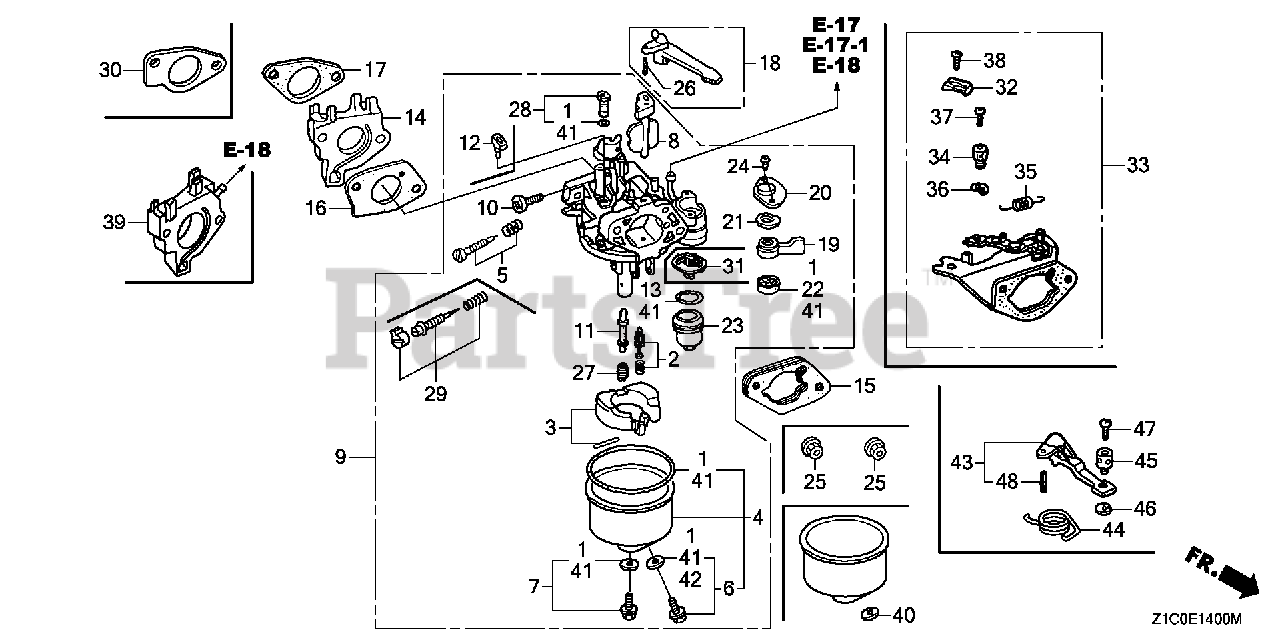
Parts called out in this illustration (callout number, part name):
2	VALVE SET, FLOAT
3	FLOAT SET (CARBURETOR NO.)
4	CHAMBER SET, FLOAT
6	SCREW SET, DRAIN (Honda Code 1672187). (CARBURETOR NO.)
7	SCREW SET
8	CHOKE SET (CARBURETOR NO.)
9	CARBURETOR ASSY. (BE85Z A)
10	SCREW, THROTTLE STOP
11	NOZZLE, MAIN (CARBURETOR NO.)
13	GASKET, FUEL STRAINER CUP
14	INSULATOR, CARBURETOR
15	SPACER, CARBURETOR
16	GASKET, CARBURETOR
17	GASKET, INSULATOR Use up to Engine SN 2949254.
18	LEVER, CHOKE (STD)
19	LEVER, VALVE
20	PLATE, LEVER SETTING (CARBURETOR NO.)
21	SPRING, PETCOCK LEVER (CARBURETOR NO.)
22	GASKET, VALVE
23	CUP, FUEL STRAINER
24	SCREW, PAN (3X6)
26	PIN, SPRING (2X12)
27	JET, MAIN (#95)
27	JET, MAIN (#100) Use from Engine SN BE87A A to BE87A A.
27	JET, MAIN (#98) Use from Engine SN BE87A A to BE87A A.
28	JET SET, PILOT (#40)
29	SCREW SET (Honda Code 4219879). (CARBURETOR NO.)
41	GASKET SET (INCLUDE 16173-001-004) (INCLUDES 16173-001-004)
